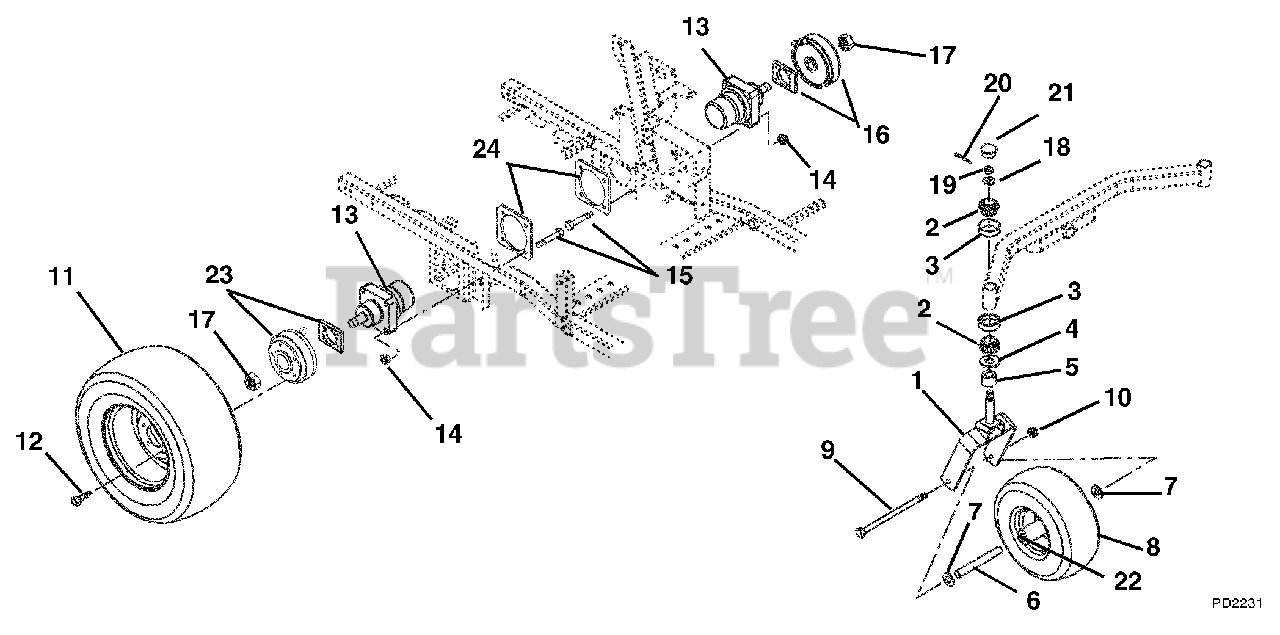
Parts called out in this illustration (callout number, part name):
1	Fork-Front
2	Bearing-Cone w/ Grease
3	Bearing-Cup 1.980 x .420
4	Bearing Seal 1.5 x 2 x .18
5	Spacer, PM, 1.03 I.D. x 1.5 O.D. x .375
6	Spacer-Wheel
7	Washer-Flat-Steel .515 x 1.625 x .250
8	Wheel/Tire Assembly
8	Tire, 15 x 6-6
9	Bolt-Hex .50-13 x 9.00 Grade 5
10	Nut-Locking-Center .50-13
11	Tire/Wheel Assembly 24 x 12-12
11	Tire, Turfmaster 24 x 12-12
12	Bolt, Lug .50-20 x 1.38 Grade 8, 60 Degree
13	Hydraulic Wheel Motor
14	Nut-Locking-Nylon .50-13
15	Bolt, Wheel Motor .50-13 x 2.75
16	Brake, Right Hand Park
17	Nut -Lock Jam Patch
18	Washer-Flat-Steel .755 x 1.375 x .062
19	Nut-Slotted .75-16
20	Pin-Cotter .16 x 1.00
21	Cap-Dust
22	Bearing, 25mm I.D. x 52mm OD x 15mm
23	Brake, Left Hand Park
24	Plate, Motor Support
